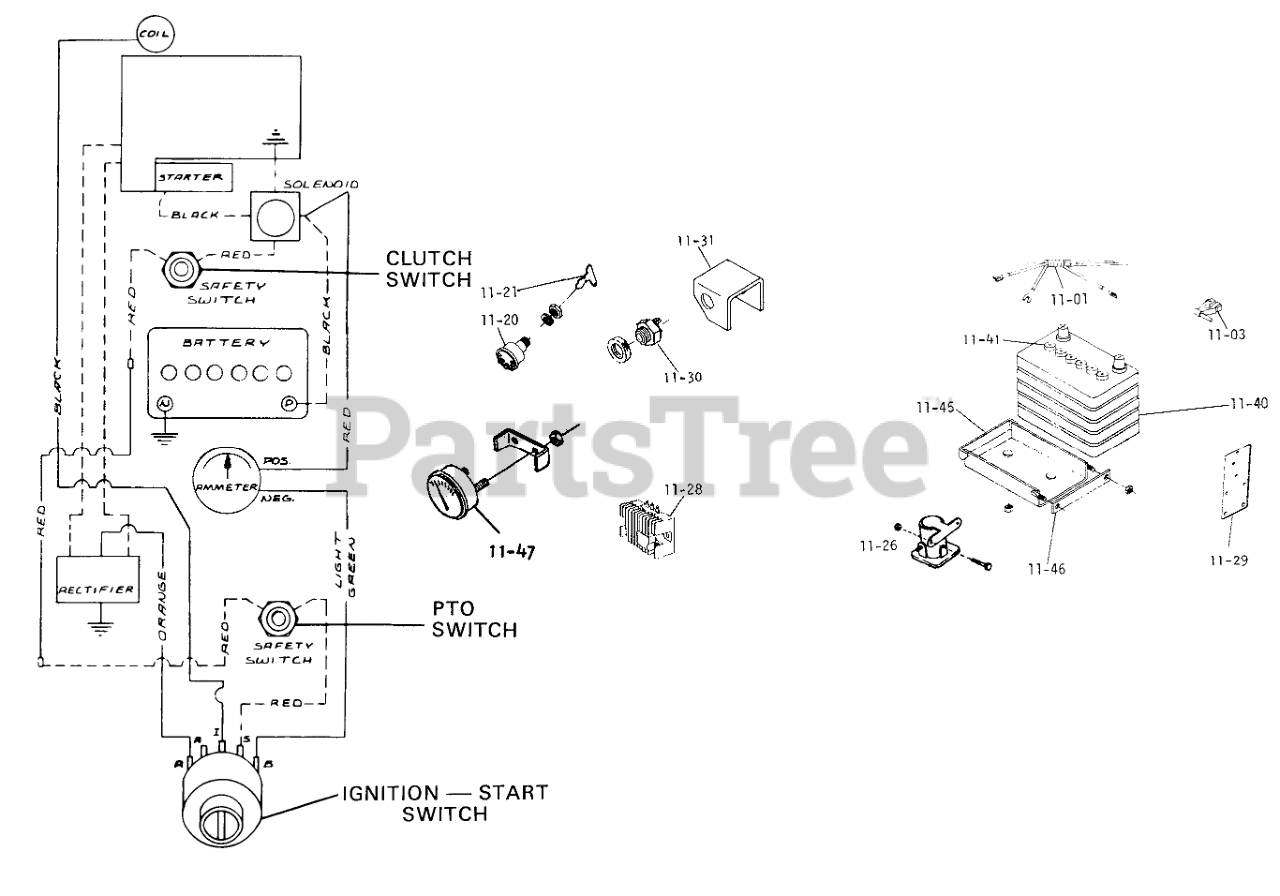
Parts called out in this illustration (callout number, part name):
11-01	WIRE HARNESS
11-02	Grommet
11-03	Wire
11-04	Wire
11-05	Wire
11-06	WIRE ASSY
11-07	Wire Assy.
11-20	SWITCH-IGNITION
11-21	Key-EL
11-26	Solenoid
11-28	REGULATOR-RECTIFIER
11-29	PLATE COIL & SOL MTG
11-30	SWITCH SAFETY
11-31	Bracket
11-40	Battery
11-45	Battery Box
11-46	LINK BATTERY CLAM R
11-47	AMMETER W/CLAMP
